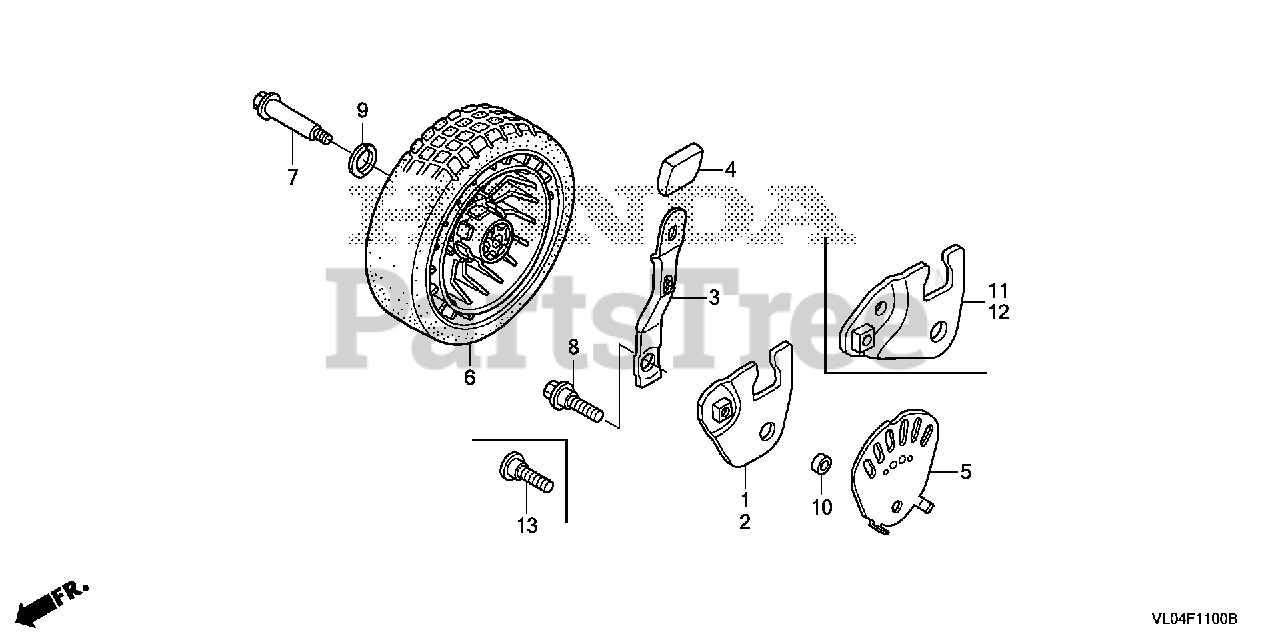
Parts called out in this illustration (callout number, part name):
3	PLATE, FR. ADJUSTER
4	GRIP, ADJUSTER *NH164* (GRIP GRAY)
5	PANEL, FR. ADJUSTER
6	WHEEL, FR. *NH164* (GRIP GRAY)
7	BOLT, FR. WHEEL SHAFT
9	WASHER, WHEEL
10	COLLAR, FR. ADJUSTING
11	ARM, R. FR. ADJUSTER
12	ARM, L. FR. ADJUSTING
13	BOLT, ADJUSTER ARM
